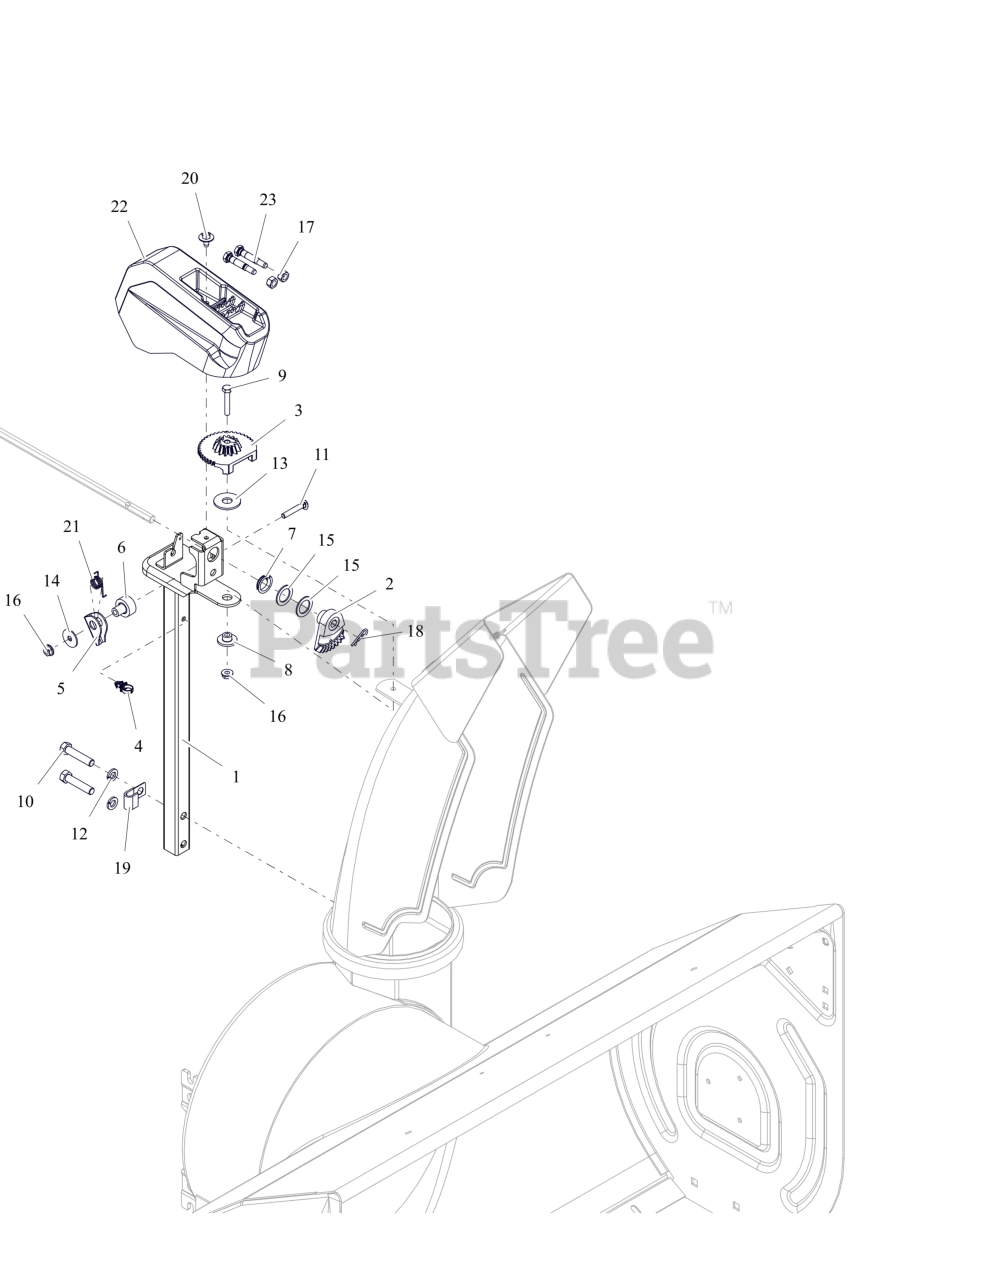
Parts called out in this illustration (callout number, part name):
1	PEDESTAL, CHUTE - QUICK STICK
2	GEAR, CHUTE-ACTUATION
3	GEAR, CHUTE
4	CLIP, CABLE GUIDE
5	ARM, LOCKING
6	BUSHING, LOCK ARM
7	BUSHING, POLYLINER-.75 SNAPIN
8	BSHG-FLG .265X.477X.375X1.00
9	BLT, HEX .25-20X1.50 G5 ZCC
10	BLT, HEX .38-16X1.75 G5 ZCC
11	BLT, RHSN .25-20X1.50 G5 ZCC
12	WSHR,LK-REG .375X.094 ZCC
13	WSHR-FLT-NYL .515X1.375X.093
14	WSHR,FLT .281X1.000X.063 ZCC
15	WSHR, FLT .754X1.125X.062 ZCC
16	NUT-LK-CTR-FLG .25-20 ZC120
17	NUT,LK-CTR .31-18 GA ZCC
18	PIN, HAIR #213 .08X1.19 ZCC
19	J-CLAMP
20	SCR, TAP .25-20X.50 LG HWH ZCC
21	SG-TORS
22	COVER, CHUTE PEDESTAL
23	SHEAR BOLT SERVICE ASSEMBLY (INCLUDES NUT)
